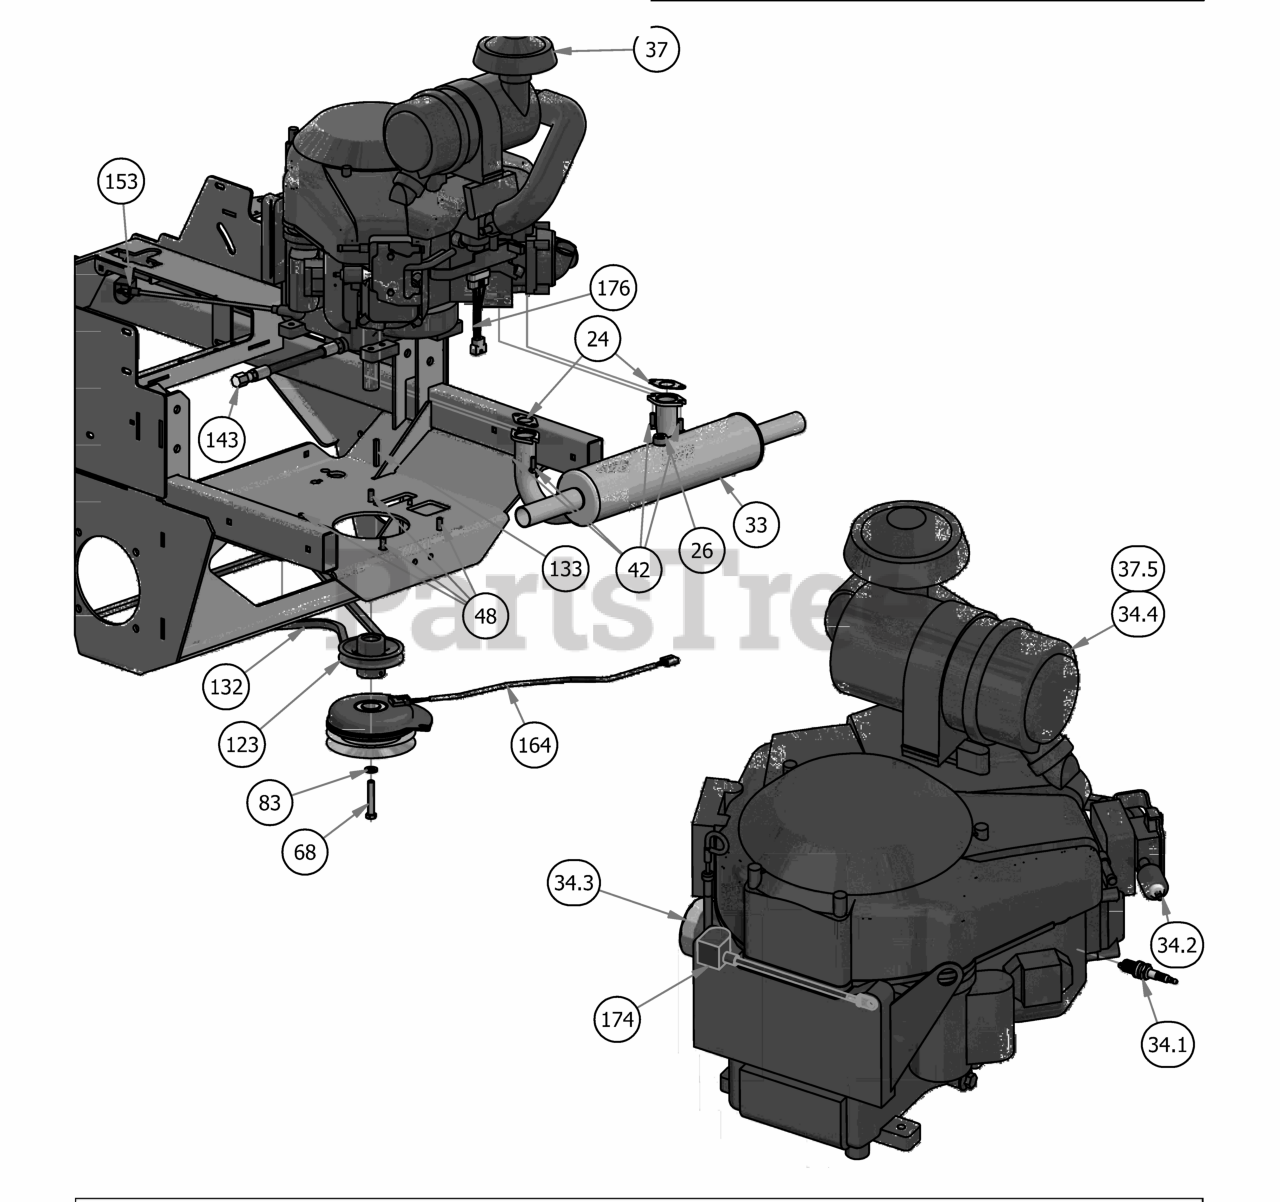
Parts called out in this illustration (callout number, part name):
24	Exhaust Gasket for 23 Vanguard
26	O2 Sensor Plug
33	Muffler for 36Hp Vanguard
34.1	Spark Plug
34.2	Universal Inline Fuel Filter
34.3	Oil Filter
34.4	Canister Air Filter- Outer
37	993cc Vanguard Engine
37.5	Canister Air Filter- Inner
42	Torx Bolt-Exhaust
48	3/8 x 1 1/8 bolt
68	7/16" x 2 1/2" Hex Bolt
83	7/16" Lock Washer
123	4 3/4 Motor Pulley
132	2019 Rebel Pump Belt
133	1/4 x 2 Square key Stock
143	14 mm Oil drain Hose 993cc Vanguard
153	14" Red Battery Cable-Base Outlaw
163	Clutch Assembly
164	Clutch Pigtail
165	2019 Rigid Frame
174	Starter Cable
176	2019 Harness Adaptor - 36 Vanguard Carberated
